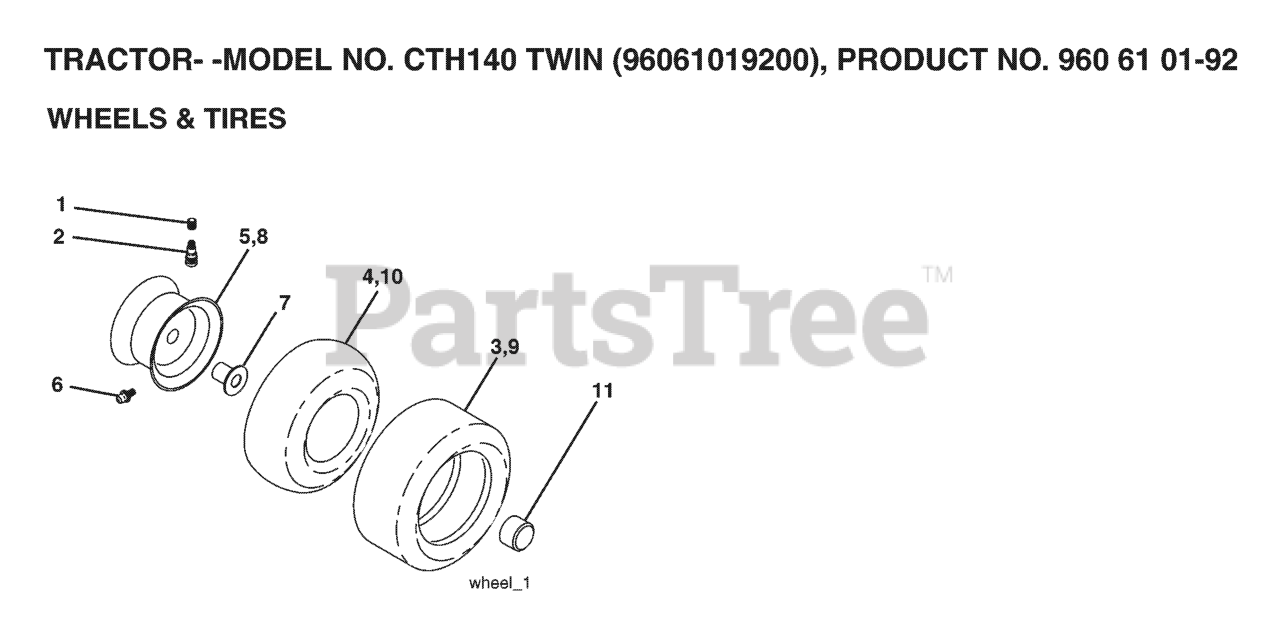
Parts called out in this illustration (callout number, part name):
2	VALVE STEM LT
3	TIRE HEAVY DUTY
4	TUBE.5.3/4.5/6
5	RIM ASM 6" FRONT SILVER
6	FITTING LT
7	BEARING T
8	RIM ASM 8" REAR SILVER
9	TIRE.TS.20X10-8
10	TUBE
11	CAP, AXLE BLK
